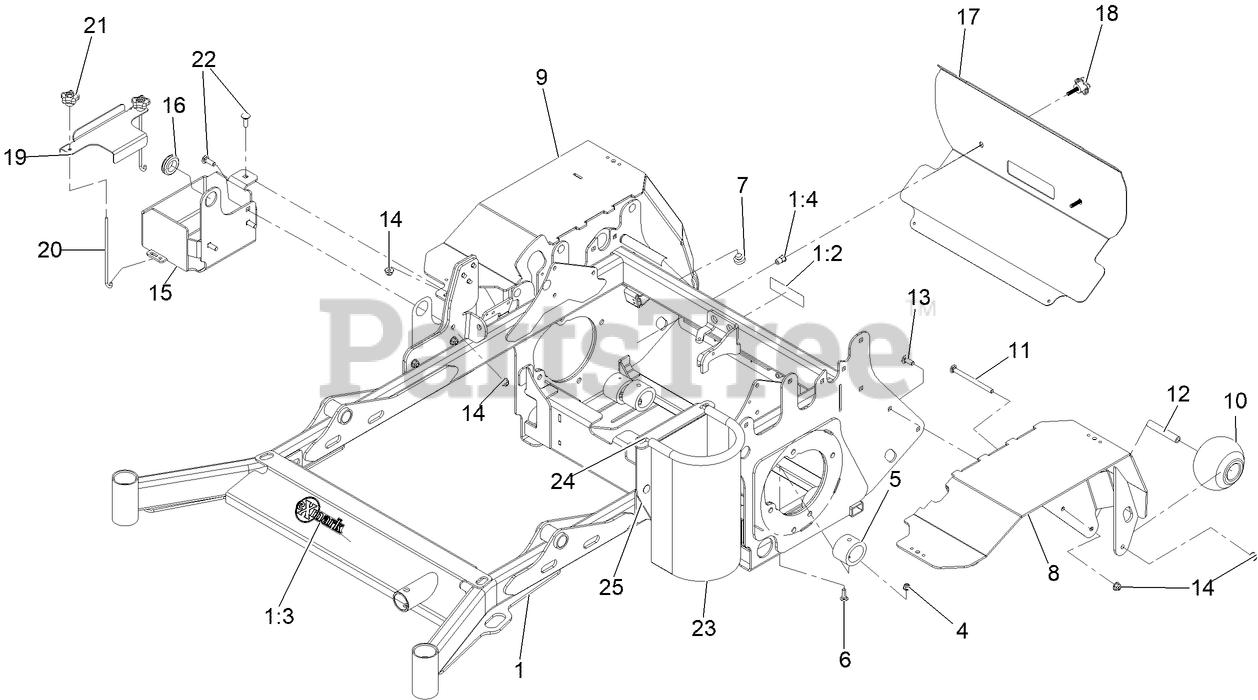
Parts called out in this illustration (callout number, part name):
1	ASM-Frame Stand On 60
1:2	DECAL-COVER, MISSING
1:3	DECAL-EXMARK LOGO
1:4	NUT-CLINCH
4	NUT-HF, NI
5	BUMPER-ISOLATOR
6	BOLT-CARR
7	BUMPER-RUBBER
8	FENDER-LH WELDT
9	FENDER-RH WELDT
10	ROLLER-SCALP, ANTI
11	BOLT-CARR
12	SPACER- ROLLER
13	SCREW-CARR
14	NUT-HF, NI
15	BATTERY TRAY
16	GROMMET
17	GUARD-REAR FOOT
19	BRACKET-BATTERY HOLD DOWN
20	BOLT-HOLDDOWN
21	KNOB-HANDLE
22	Bolt-Carriage 3/8-16 X 1 1/4
23	BAG-TRASH
24	ROD-BAG, TRASH
25	BRACKET-TRASH BAG MOUNT
